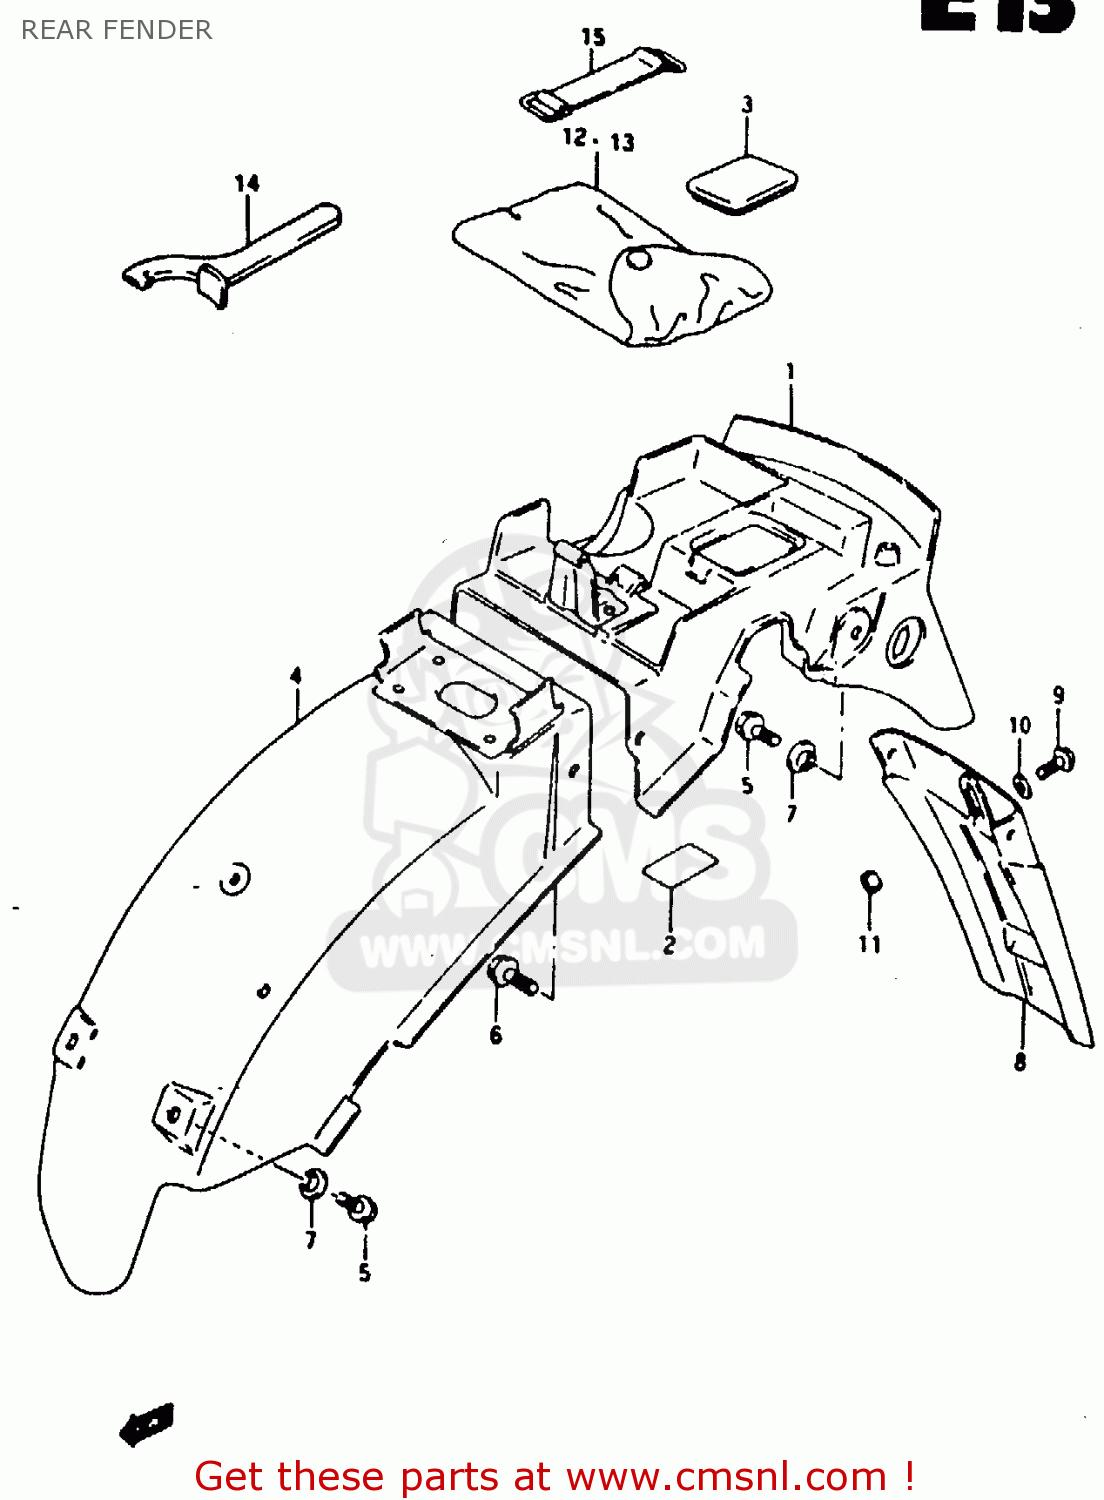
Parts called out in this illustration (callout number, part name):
1	BODY, REAR FENDER REAR
2	TAPE,RR FENDER
3	CAP,RR FENDER RR
4	BODY, REAR FENDER FRONT
5	BOLT
6	BOLT
7	WASHER
8	EXTENSION, REAR FENDER
9	SCREW
10	WASHER(6.5X16X1.2)
11	NUT
12	TOOL ASSY
13	TOOL ASSY
14	CLAMP
15	BAND
